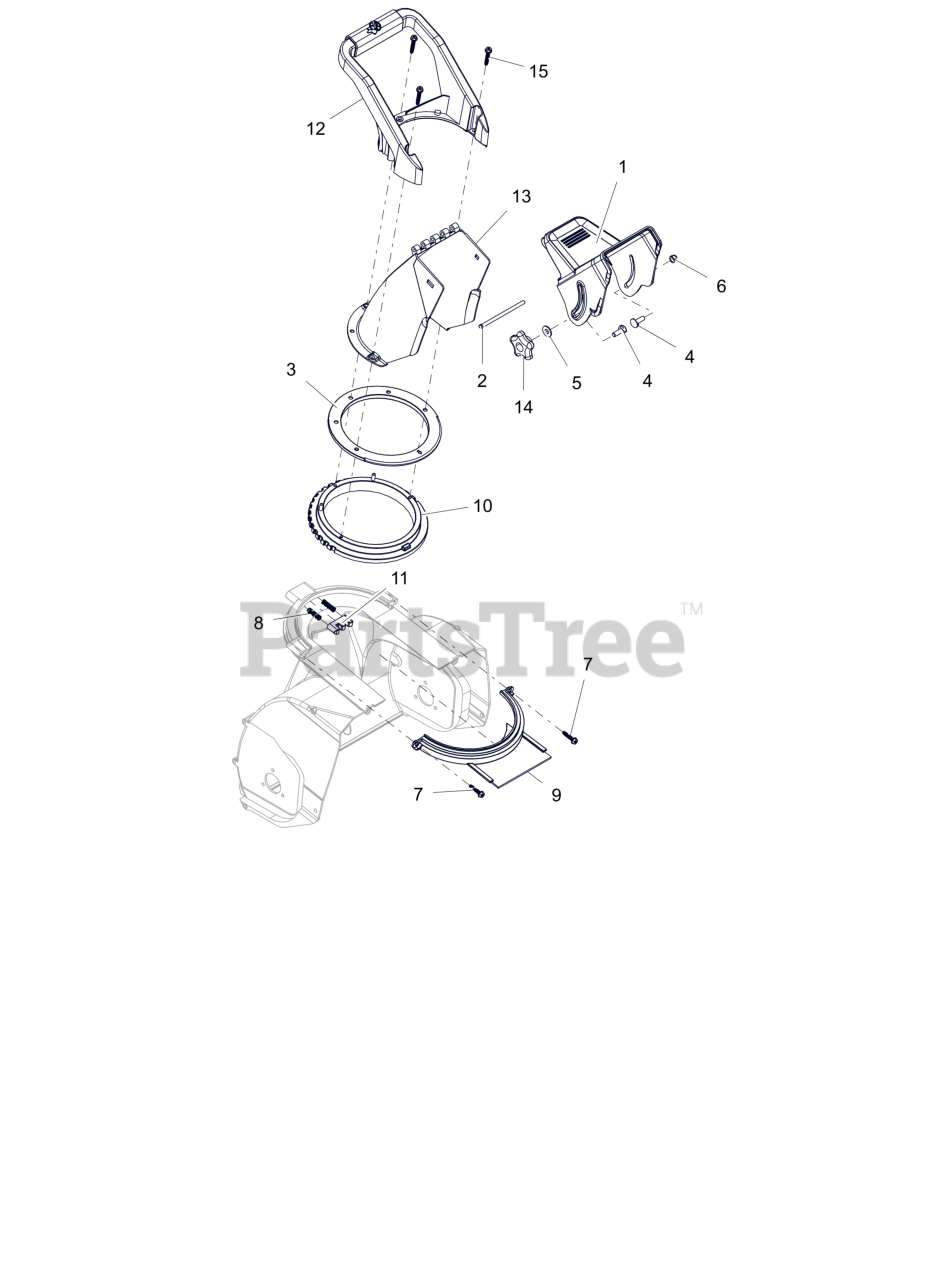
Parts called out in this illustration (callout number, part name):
1	KIT, CAP REPLACEMENT
2	ROD, CONNECTING, 1/4 X 4-1/2
3	GUARD, WATER
4	BLT,RNHDRECSHNK .31-18X1.00
5	WSHR, FLAT .375X.875X.065 (BLACK)
6	NUT, NYLON .313-18 (BLACK)
7	1/4"-10x1.12 TRI-LOBE SCREW
8	SPRG, COMPRESSION
9	CHUTE, RETAINER
10	GEAR, CHUTE
11	PAWL, CHUTE DETENT
12	HANDLE, CHUTE
13	CHUTE, DISCHARGE
14	.321-18 KNOB
15	.25-10x1.12 TRI-LOBE SCREW
